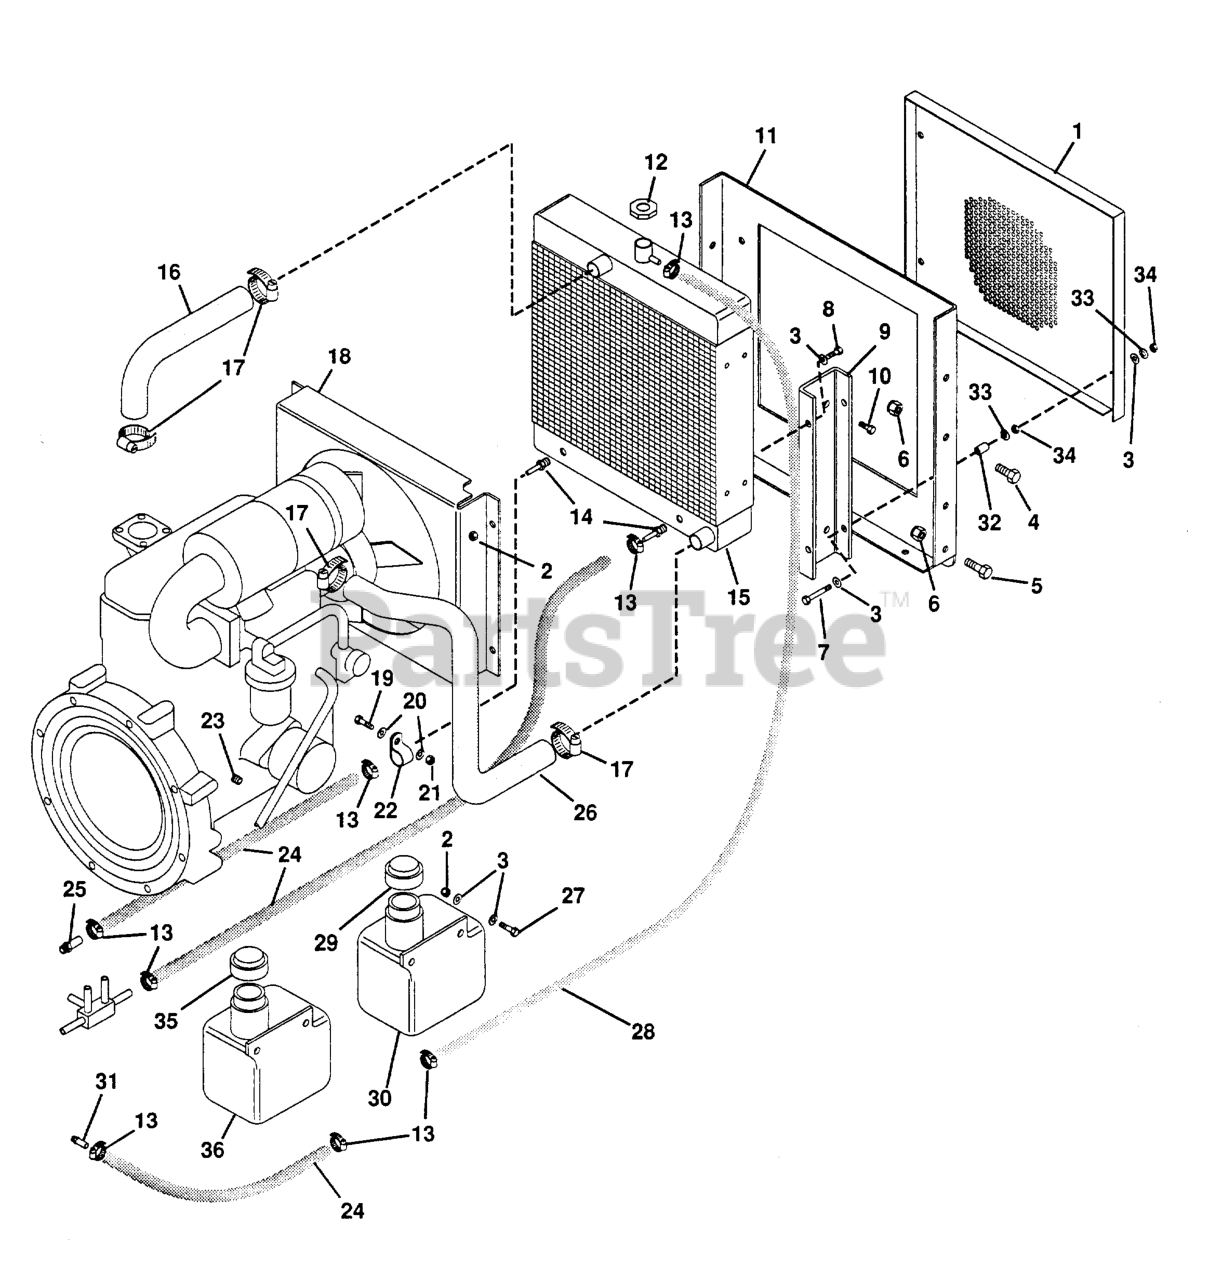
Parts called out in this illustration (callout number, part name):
1	Cover, Air
2	Nut, Lock 5/16-18
3	Washer, Flat .344x.688x.065
4	Bolt, Hex 1/2-13x1.00
5	Bolt, Hex 1/2-13x1.50
6	Nut, Lock 1/2-13
7	Bolt, Hex 5/16-18x2.00
8	Bolt, Hex 5/16-18x.75
9	Bracket, Radiator
10	Bolt, Hex 5/16-18x.50
11	Mount, Radiator
12	Cap, Radiator
13	Clamp, Hose
14	Adapter, #4404-6-6
15	Radiator, Flat Plate
16	Hose, Upper Radiator
17	Clamp, Hose
18	Cover, Fan
19	Bolt, Hex 3/8-16x1.00
20	Washer, Flat .406x.812x.065
21	Nut, Lock 3/8-16
22	Clamp, Nylon
23	Plug, PT 1/4
24	Hose, Hydraulic
25	Adapter, #4604-6-6
26	Hose, Lower Radiator
27	Bolt, Hex 5/16-18x1.00
28	Hose, 5/16 ID
29	Cap, 1-5/8 Vented(Black)
30	Tank, Plastic 1.5 Qt.
31	Connector, Hose
32	Stop, Chute
33	Washer, Lock 5/16 Reg.
34	Nut, Hex 5/16-18
35	Cap, Non-Vented(White)
36	Tank, Non-Vented
NS	Decal, Danger Hand
